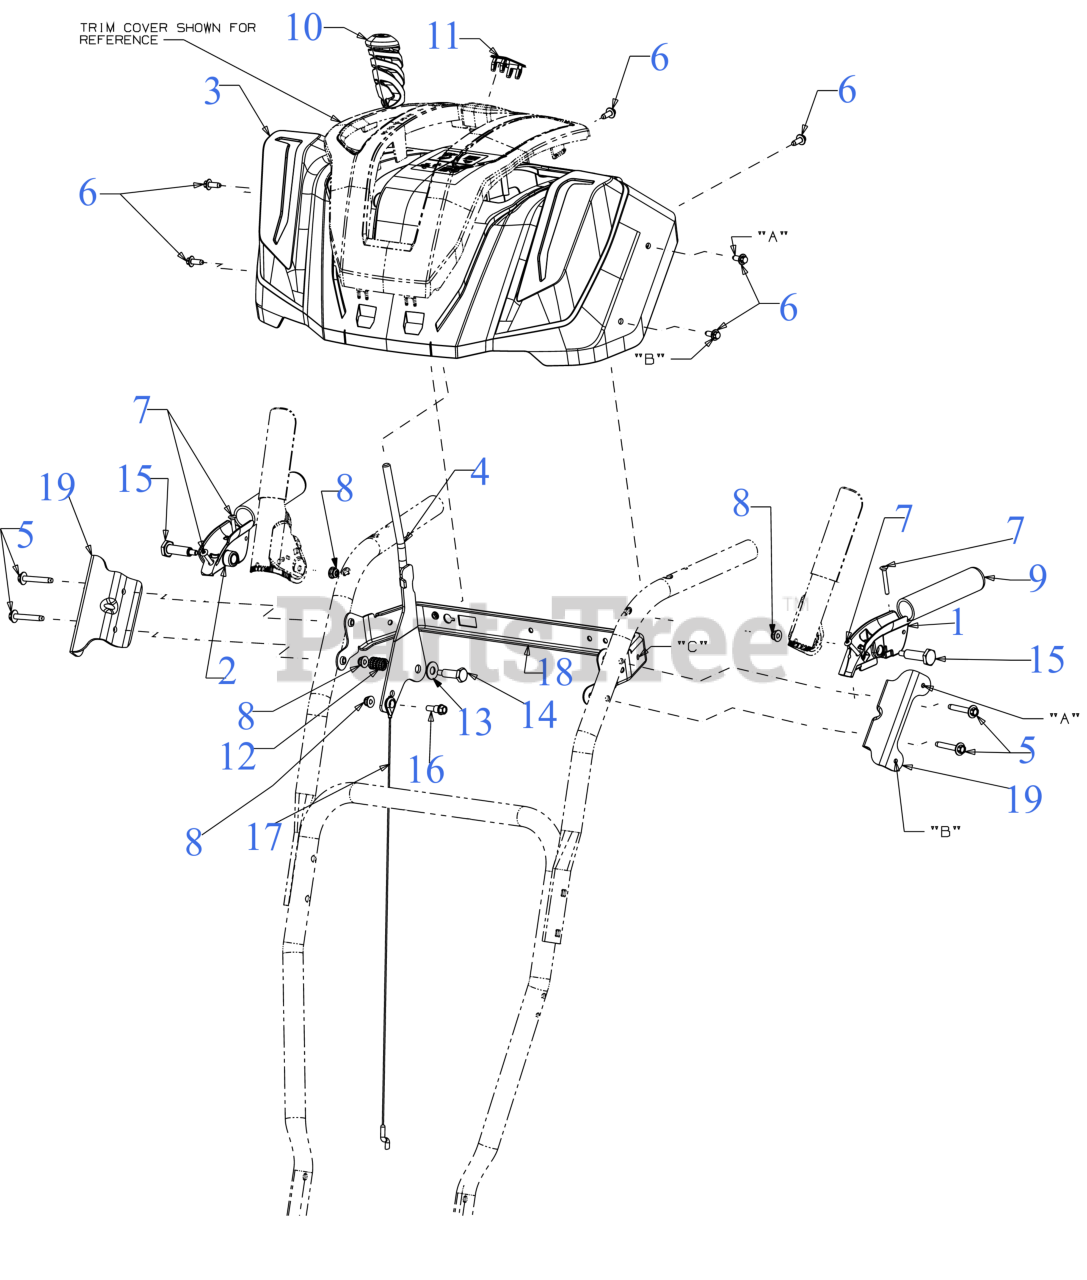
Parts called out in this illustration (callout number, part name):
1	CLUTCH LOCK HANDLE ASSEMBLY (LH)
2	CLUTCH LOCK HANDLE ASSEMBLY (RH)
3	HANDLE PANEL
5	SCREW 1/4-20 x 1.625
6	SCREW M6-1 x .625
7	SCREW #10-24 x 1.375
8	FLANGE LOCK NUT
10	PTO HANDLE GRIP .355 ID
11	PANEL SWITCH PLUG
12	COMPRESSION SPRING
13	FLAT WASHER .38X.88
14	SHOULDER SCREW
15	SHOULDER SCREW .437 x 1.345 1/4-20
16	SHOULDER SCREW .342X.335X1/4-20
17	SELECTION CABLE
